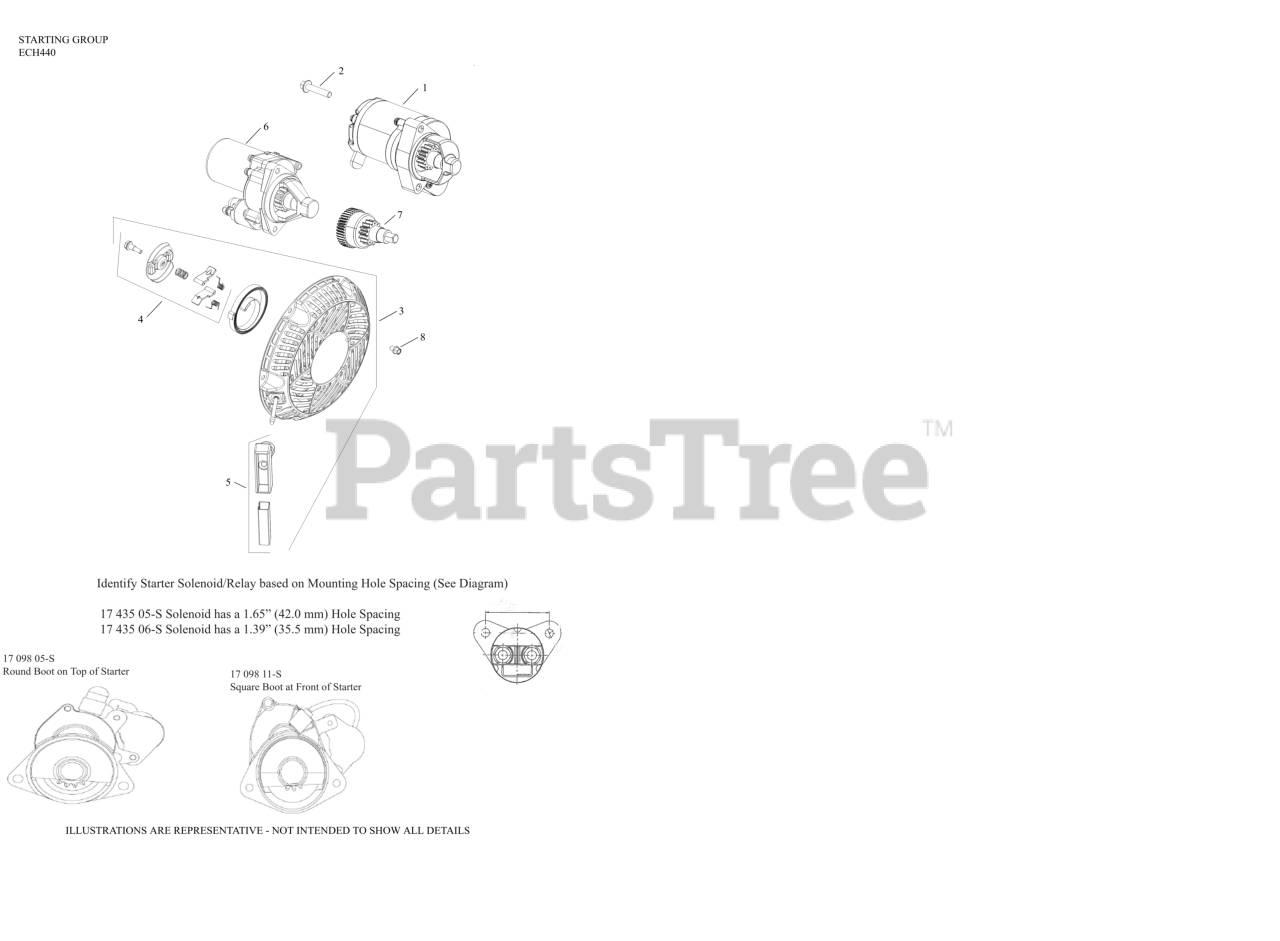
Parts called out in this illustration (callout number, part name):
3	RETRACTABLE STARTER ASSY-(#1716522S)
4	KIT, PAWL REPAIR
5	KIT, HANDLE
6	ELECTRIC STARTER-BENDIX DRIVE
7	KIT, STARTER DRIVE
